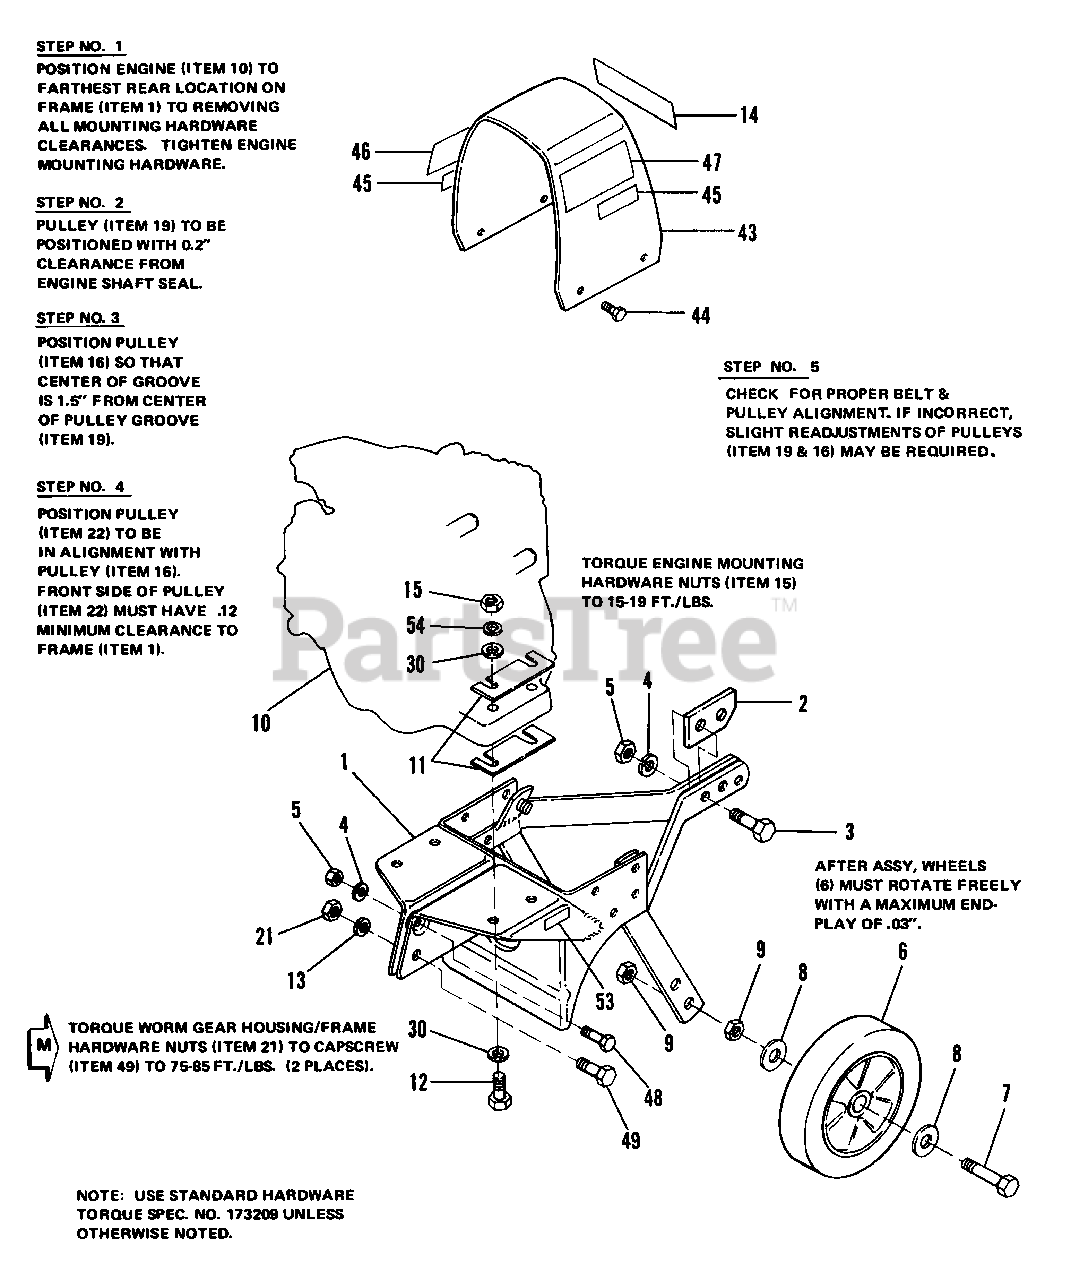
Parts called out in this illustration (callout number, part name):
1	FRAME ASSY
2	STOP, Plate
3	CAPSCREW, Hex, 3/8-16 x 1-1/2
4	LOCKWASHER, 3/8
5	NUT, Hex, Full, 3/8-16
6	WHEEL & TIRE ASSY
7	CAPSCREW, 1/2-13 x 3-1/2
8	WASHER, Plain, 1/2
9	NUT, Hex, Jam, 1/2-13
12	CAPSCREW, Hex, 5/16-18 x 1-3/4
13	LOCKWASHER, 7/16
14	DECAL, Simplicity
15	NUT, Hex, 5/16-18
16	PULLEY, Engine, Forward
17	KEY, Sq., 3/16 x 1
18	SCREW, Set, 5/16-18 x 5/16
19	PULLEY, Engine, Rev.
20	KEY, 1/8 x 5/8, No. 5
21	NUT, Hex, Full, 7/16
22	PULLEY, Drive
24	V-BELT, Reverse
25	BELT, Forward
26	LEVER, Idler Pulley
29	CAPSCREW, Hex, 3/8-16 x 1-3/4
30	WASHER, Plain, 5/16
31	PULLEY, Idler
33	CAPSCREW, Hex, 3/8-16 x 1-1/4
34	LOCKNUT, Hex, Jam, 3/8-16
35	BOLT, Pivot
36	LOCKNUT, Flange, Whiz, 5/16-18
37	BELLCRANK
38	LINK, Rod
39	PIN, Cotter, 1/16 x 3/4
40	LOCKNUT, Hex, Flange, 5/16-18
41	STOP, Belt
42	CAPSCREW, Hex, 3/8-16 x 1
43	COVER, Engine
44	SCREW, Taptite, 1/4-20 x 3/8
45	DECAL, 1005
46	DECAL, Roticul, R.H.
47	DECAL, Roticul, L.H.
48	CAPSCREW, Hex, 3/8-16 x 3/4
49	CAPSCREW, Hex, 7/16-20 x 1-1/4
50	CLAMP, Wire
51	SCREW, Set, No. 10-24 x 5/8
52	WASHER, Plain, 3/16
53	I.D. PLATE
54	LOCKWASHER, Spring, 5/16
